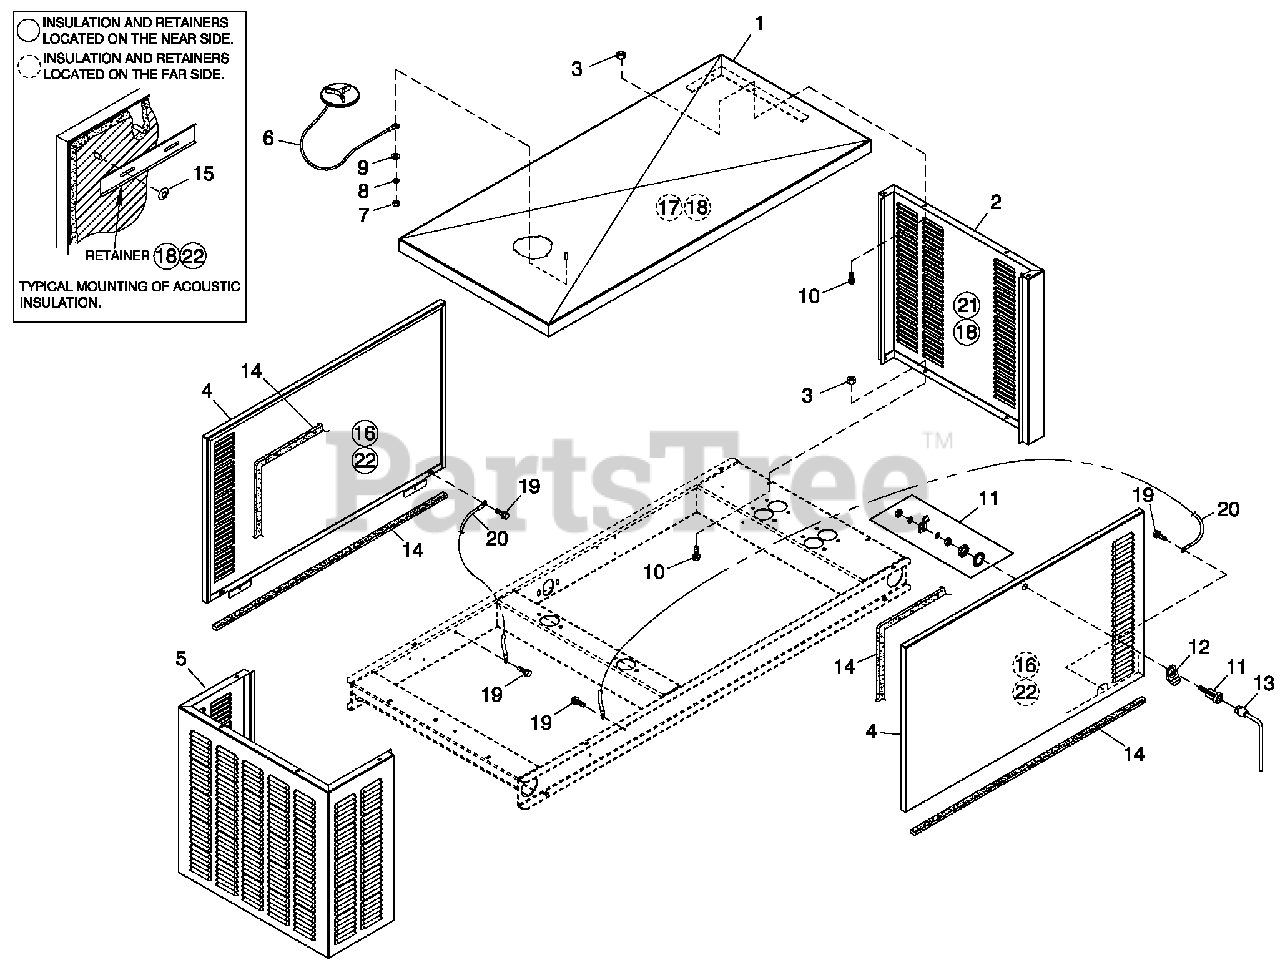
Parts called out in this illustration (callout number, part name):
1	ROOF 1.6L C1
2	REAR INTAKE WRAP 1.6L C1
3	NUT HEX LOCK M6-1.0 SS NY INS
4	RIGHT SIDE DOOR 1.6L C1
5	FRONT DISCHARGE WRAP 1.6L C1
6	ASSY ACCESS COVER
7	NUT HEX 1/4-20 STEEL
8	WASHER LOCK M6-1/4
9	WASHER FLAT 1/4-M6 ZINC
10	SCREW THF M6-1 X 16 N WA Z/JS
11	VISE-ACTION LATCH, SLOTTED CIR
12	TAB PULL
13	KEY VISE-ACTION LATCH,SLOT CIR
14	FOAM STRIP 3/4"WIDE X 3/16"THK (294"LG)
15	WASHER SELF LOCKING DOME
16	INSULATION SIDE DOOR C1
17	INSULATION ROOF C1
18	RETAINER INSULATION (450)
19	SCREW HWHTF M6-1.0X16
20	ASSY WIRE 14AWG GRN/YEL (32.25TG)
21	INSULATION REAR C1
22	RETAINER INSULATION (820)
